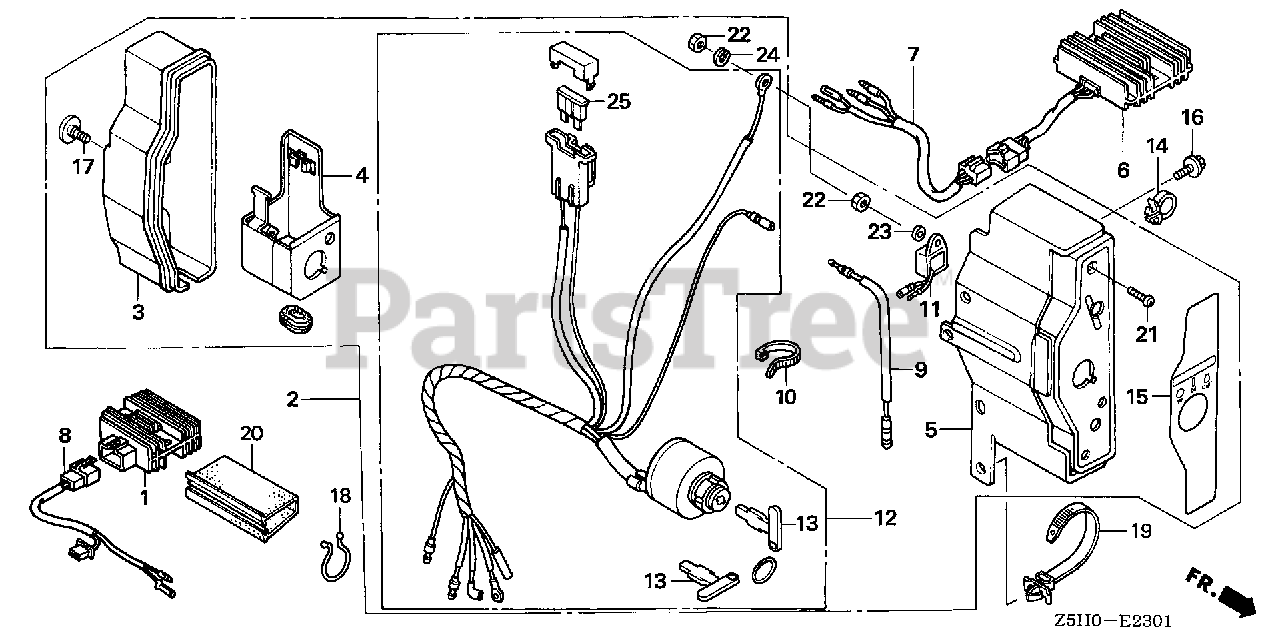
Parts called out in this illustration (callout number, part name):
1	RECTIFIER ASSY., REGULATOR (10A)
2	BOX ASSY., CONTROL (10A) *R280* (EXP-ALERT) (POWER RED)
3	CASE, CONTROL
4	BRACKET, CASE MOUNTING
5	PANEL, CONTROL *R280* (POWER RED)
8	SUB-WIRE HARNESS ASSY.
9	SUB-WIRE HARNESS
11	ALERT UNIT, OIL
12	SWITCH ASSY., COMBINATION (10A-CHARGE)
13	KEY (HONDALOCK)
14	HOLDER, STOP SWITCH WIRE
15	MARK, CONTROL BOX (EXP)
16	BOLT, FLANGE (6X12) (CT200)
17	SCREW, SPECIAL (6X12)
18	CLIP, PURSE LOCK
19	STRAP, CABLE (118MM) (BLACK)
20	TUBE, FASTENER (30MM)
21	SCREW, PAN (4X12)
22	NUT, HEX. (4MM) (SOURCE: VINTAGE PARTS INC.)
23	WASHER, PLAIN (4MM)
24	WASHER, SPRING (4MM)
25	FUSE, BLADE (15A)
